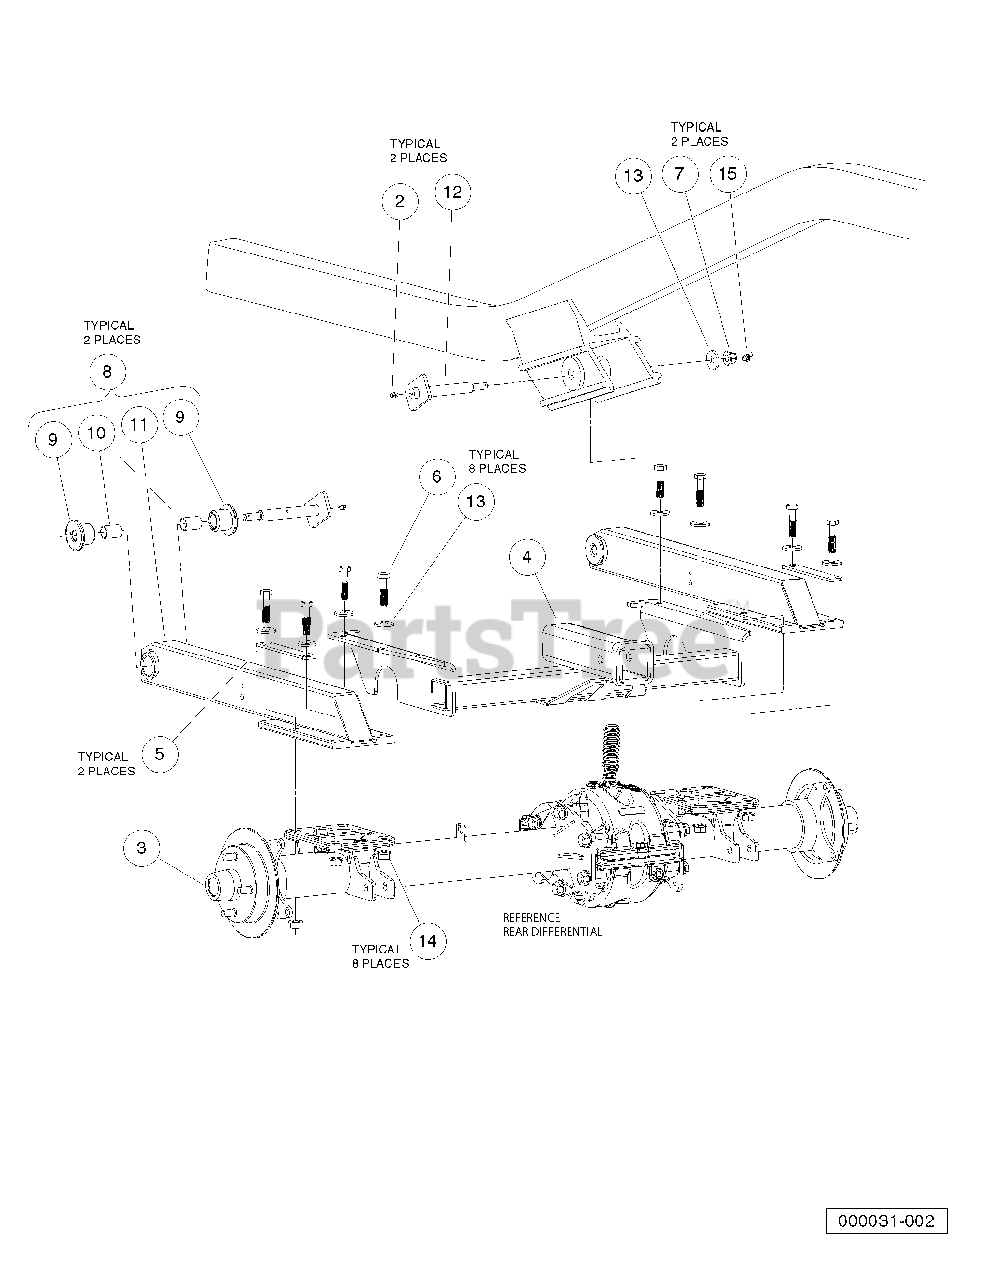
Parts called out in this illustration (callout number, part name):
1	Instl, Rear Suspension
2	Fitting, 1/4-28 Thread-Forming Grease
3	Center Cap, Rubber
4	Weldment, Receiver, Rear
5	Washer, Strip, Swingarm
6	Bolt Flanged Head, M12 X 1.75 X 50
7	Nut Flg, M12x1.75, Nylon Gr 10
8	Sub Asm Swingarm
9	Bushing, Pivot, Urethane
10	Bushing, Teflon
11	Swingarm, Rear, Awd
12	Pin, Swingarm, Weldment
13	Washer, M12 Hard Regular
14	Nut Flg M12 X 1.75 Cl10
15	Cotter, Rue Ring, 1/2"
